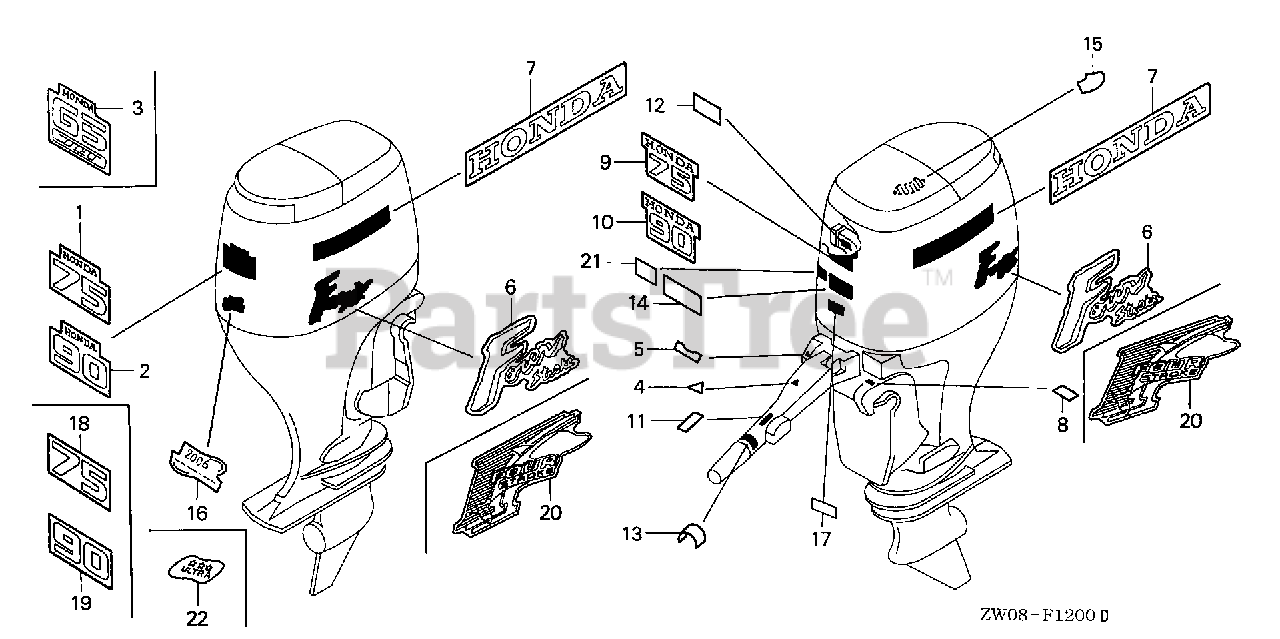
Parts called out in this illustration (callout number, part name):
7	MARK, SIDE STRIPE
8	LABEL, SPECIFICATION (NMMA)
12	LABEL, OIL CAUTION (ENGLISH)
14	LABEL, CAUTION OPERATOR (ENGLISH)
15	MARK, EMERGENCY START (ENGLISH)
17	MARK (E-SPEC)
19	MARK, RR. (90)
20	MARK, SIDE
